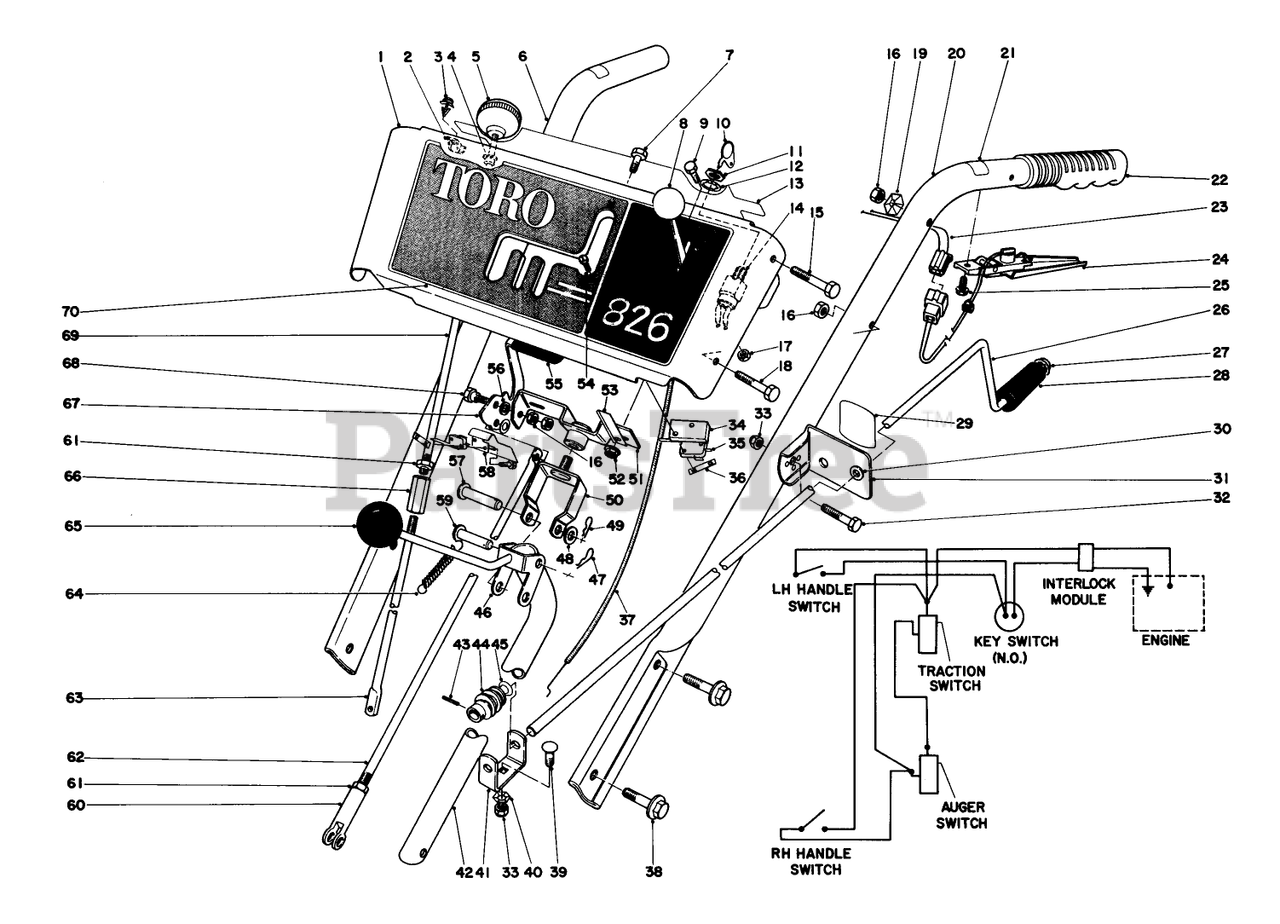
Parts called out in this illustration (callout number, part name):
4	NYLINER #6LI-FF TYPE 7
5	KNOB-LEVER
7	SCREW-HH
11	NUT-HH
12	SCREW-SET
15	SCREW-HH
16	NUT-LOCK, CONE
18	SCREW-HH
25	SCREW
27	NUT-PUSH
28	GRIP-CONTROL, CHUTE
32	SCREW-HH
33	NUT-LOCK, NI
35	SWITCH-MICRO
36	Speed Nut
38	SCREW-HHF
39	BOLT-CARR
40	WASHER-LOCK
43	PIN-SPRING
44	GEAR-WORM, CHUTE
45	WASHER-SPRING
46	SHIFT ROD WA
48	WASHER-FLAT
49	PIN-HAIR
52	NUT-LOCK, HHF
54	SCREW-SPH
56	WASHER-PLAIN
57	PIN-CLEVIS
58	SWITCH BRKT
59	PIN-CLEVIS
60	CLEVIS
61	NUT-HJ
63	LOWER WHL CLUTCH ROD
66	WHL ROD COUPLING
68	SCREW-SHOULDER
